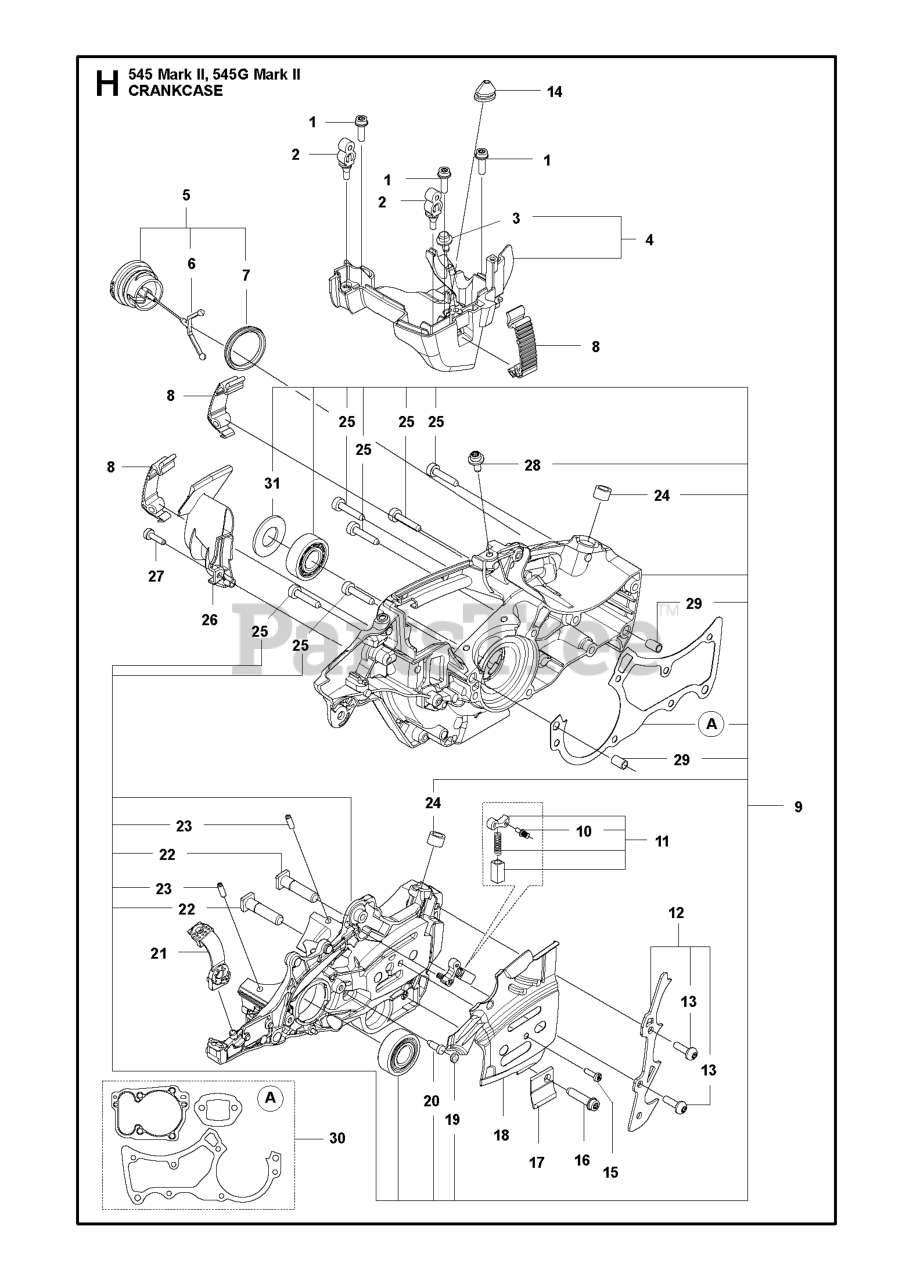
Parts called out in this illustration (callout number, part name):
2	SUPPORT
4	CARBURETTOR AREA BASE ASSY
5	TANK CAP ASSY
8	CLIP GRAY
9	CRANKCASES
11	CATCH KIT SPARE PART
12	SPIKE KIT SPARE PART 50CC MARK
13	SCREW ITXPANM M5X16 T27 10.9
15	SCREW CITXPANT
17	CHAIN CATCHER
18	CHAIN GUIDE PLATE
19	PLUG
20	VALVE-CHECK (DUCKBILL)
21	DEFLECTION LIMITER
23	PARALLEL PIN
24	SLEEVE CERAMIC
26	AIR NOZZLE
27	SCREW ITXSCM M4X15 T27 12.9 T
28	SCREW ITXSCM WASHER M5X12 T27
29	GUIDE BUSHING
30	GASKET KIT MARK II
